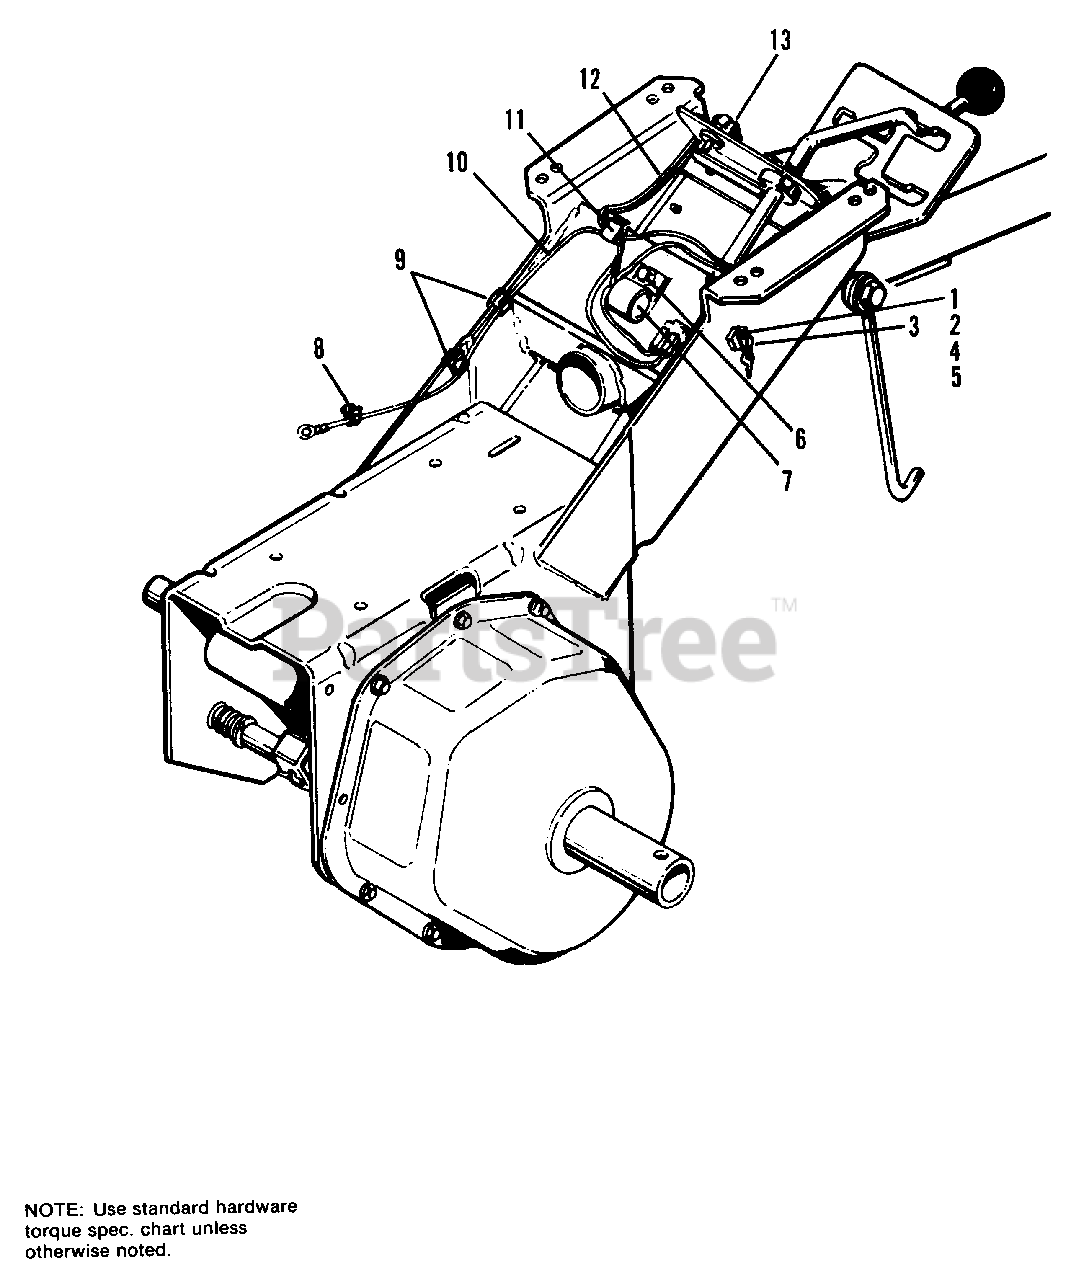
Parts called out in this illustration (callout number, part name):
1	SWITCH, Ignition
3	KEY & RING ASSY.
4	LOCKWASHER, 5/8
5	NUT, Hex
6	SCREW, Hex, Self Tapping, 1/4-20 x 3/8
7	INTERLOCK, Ignition
13	SWITCH, Safety
